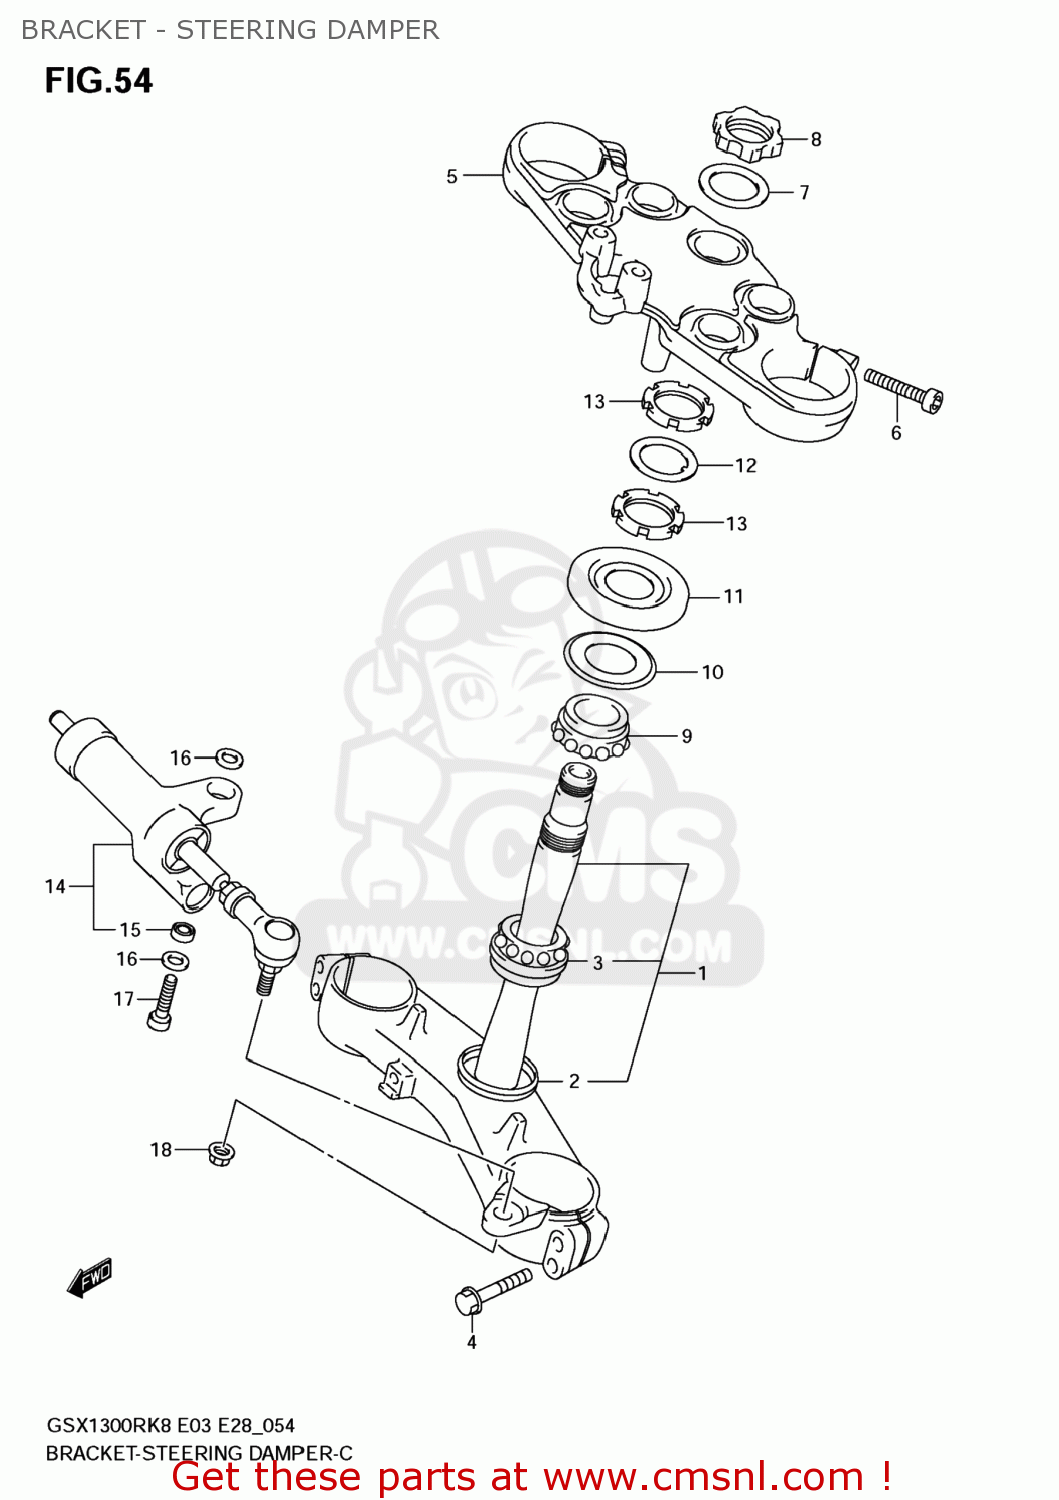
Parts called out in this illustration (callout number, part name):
1	BRACKET,FR FORK UNDER
2	SEAL,STEERING LWR
3	BEARING(30X55X17)
4	BOLT
5	BRACKET,FR FORK UPR
6	BOLT
7	WASHER
8	NUT
9	BEARING(30X55X17)
10	SEAL,STEERING LWR
11	COVER,STEERING UPR
12	WASHER,STEERING STEM
13	NUT,STEERING STEM
14	DAMPER ASSY,STEERING
15	BEARING(8X17.5X11)
16	SEAL,PILLOW BALL,DUST
17	BOLT
18	NUT
